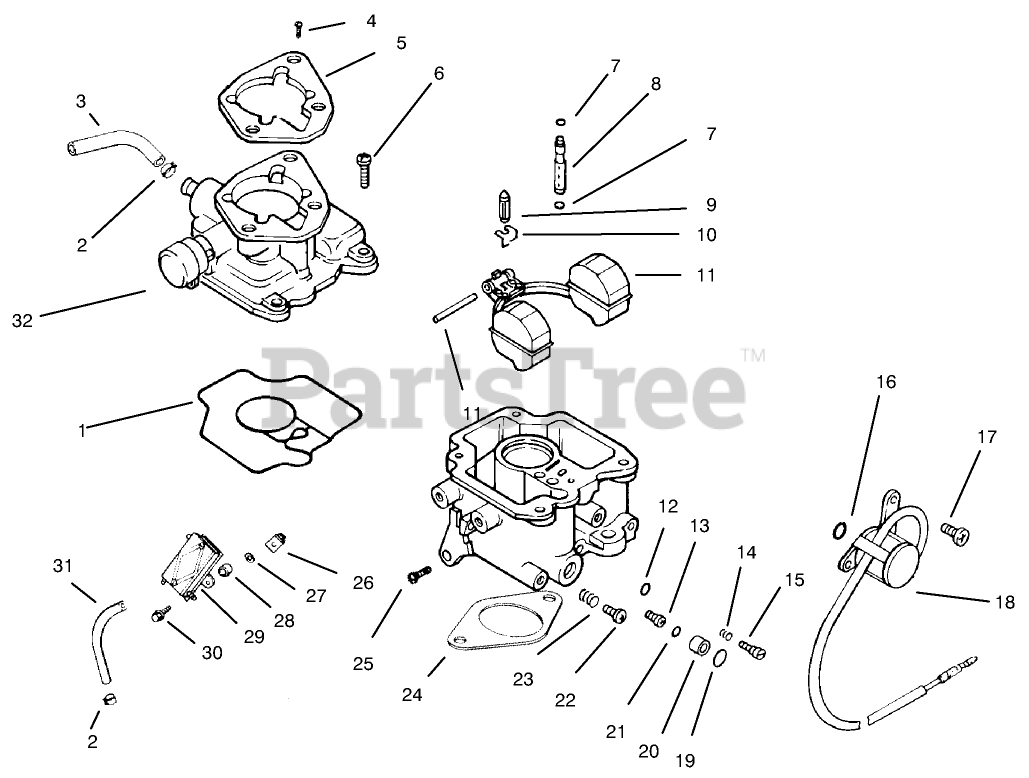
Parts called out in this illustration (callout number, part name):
1	Gasket-Body, Carburetor
2	Clamp
3	Line-Fuel 9"
5	GASKET-BASE, AIR CLEANER
9	Valve-Needle, Inlet
10	Clip-Valve, Needle Inlet
11	FLOAT REPAIR KIT
14	Spring-Needle, Idle
15	Needle-Idle
18	Solenoid ASM
20	Seat-Solenoid
22	Screw-Speed Adjust, Idle
23	Spring-Speed Adjust, Idle
24	Gasket-Carburetor
25	Screw-Stop, Throttle
26	Nut-Plastic
27	Washer-Flat (1/4)
29	Pump, fuel-pulse
31	Line-Fuel, Flexible (15.5)
32	Kit-Choke Repair (Incl. Ref. #33
